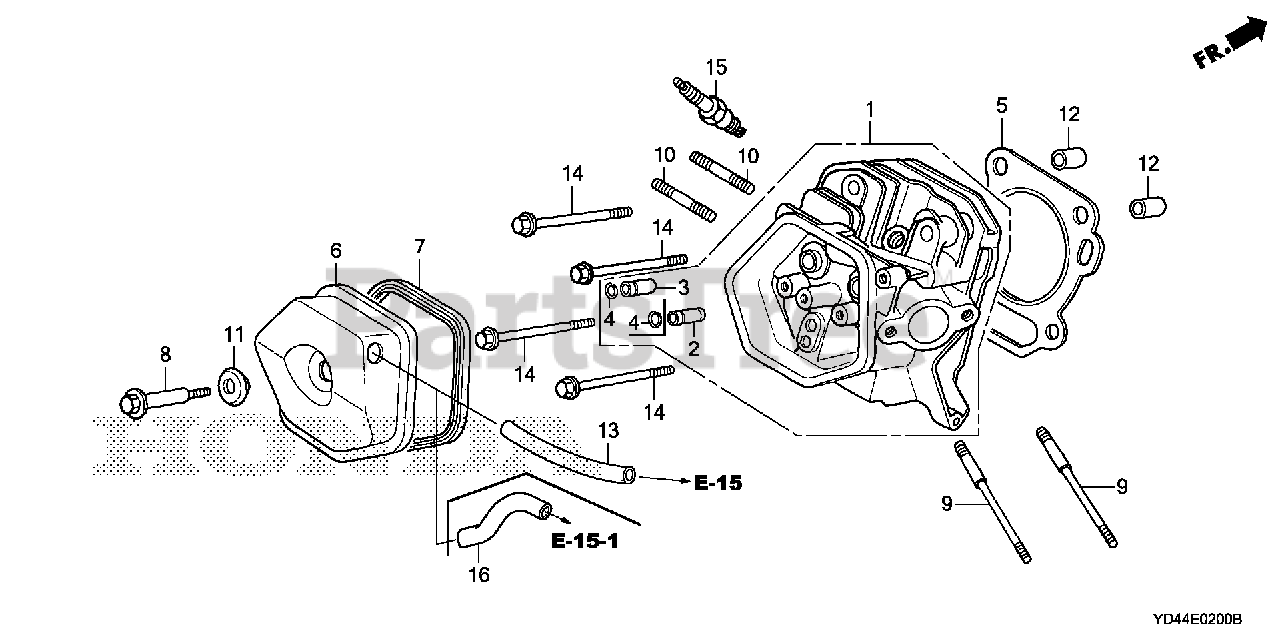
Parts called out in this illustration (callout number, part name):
1	CYLINDER HEAD
2	GUIDE, VALVE (OVER SIZE)
3	GUIDE, EX. VALVE (OVER SIZE)
4	CLIP, VALVE GUIDE
5	GASKET, CYLINDER HEAD
6	COVER, HEAD
7	GASKET, HEAD COVER
8	BOLT, HEAD COVER
9	BOLT, STUD (8X131.5)
10	BOLT, STUD (8X47)
10	BOLT, STUD (8X32)
11	WASHER, HEAD COVER
12	PIN, DOWEL (12X20)
13	BULK HOSE, VACUUM (11X1000) (11X105)
14	BOLT, FLANGE (10X80)
15	SPARK PLUG (BPR5ES) (NGK)
15	SPARK PLUG (W16EPR-U) (DENSO)
15	SPARK PLUG (BPR6ES) (NGK)
15	SPARK PLUG (W20EPR-U) (DENSO)
